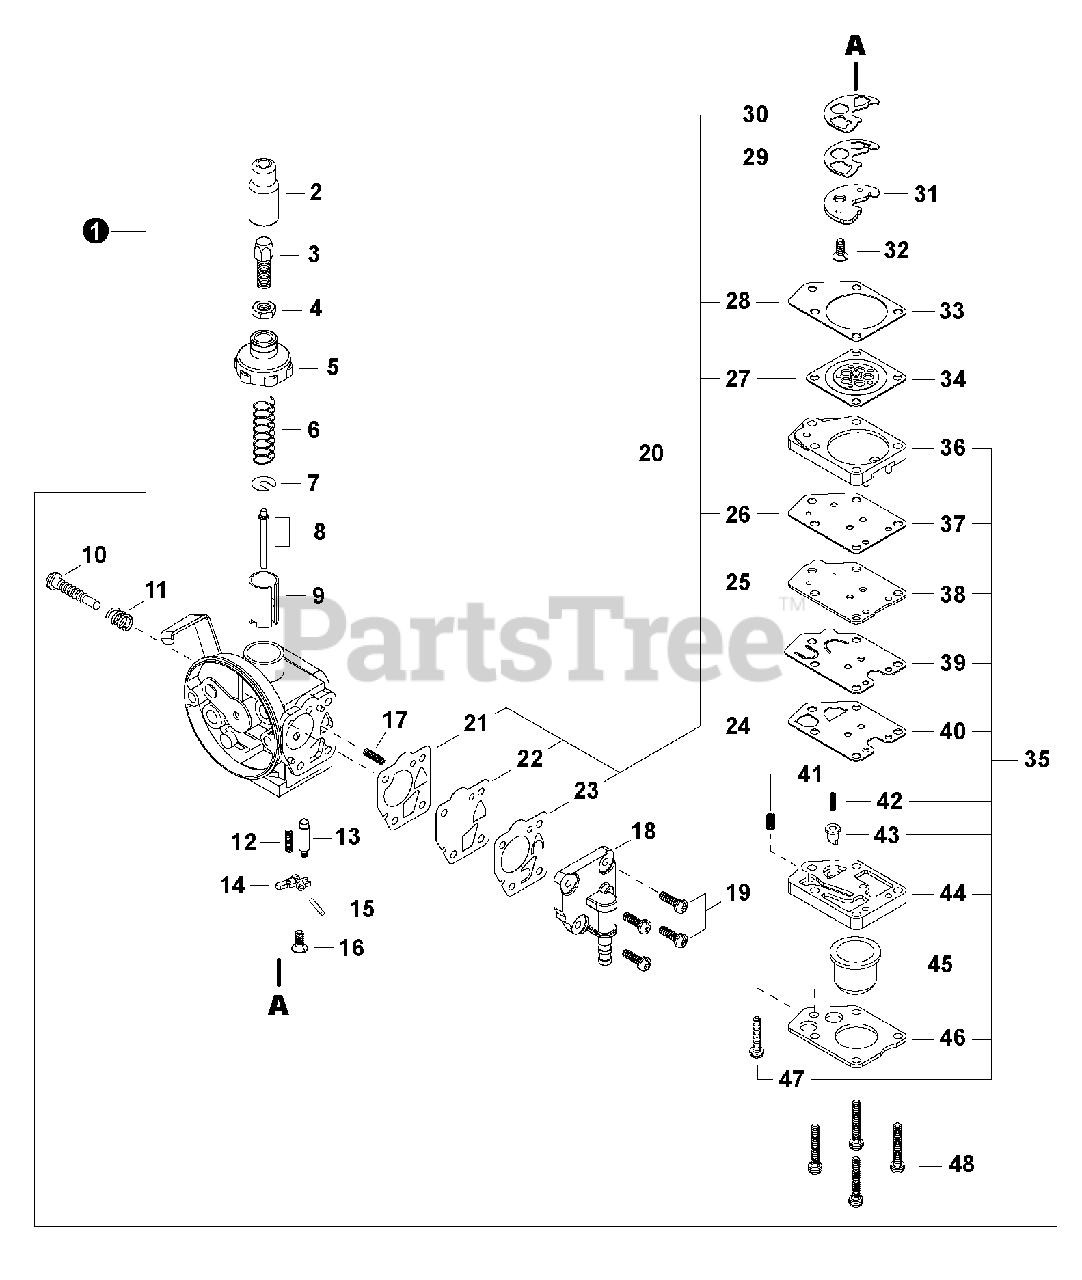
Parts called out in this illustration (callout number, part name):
1	CARBURETOR - DPV10W-18B
3	ADJUSTER, CABLE
4	NUT, LOCK
5	CAP, CARBURETOR
7	WASHER, SPRING SUPPORT
8	NEEDLE, JET
9	VALVE, THROTTLE
10	SCREW, IDLE ADJUST
12	SPRING, TENSION
13	VALVE, INLET NEEDLE
14	LEVER, METERING
15	PIN, METERING LEVER
16	SCREW M3×8
17	SPRING, COIL
18	PUMP BODY
20	GASKET / DIAPHRAGM KIT
21	GASKET, DIAPHRAGM
22	DIAPHRAGM, METERING
23	VALVE, PUMP
24	VALVE, CHECK
27	DIAPHRAGM, METERING
28	GASKET, METERING DIAPHRAGM
29	VALVE, CHECK
30	PACKING
32	SCREW M3×8
33	GASKET, METERING DIAPHRAGM
34	DIAPHRAGM, METERING
35	PURGE PUMP KIT
36	COVER, PUMP
39	PLATE, PUMP
40	VALVE, CHECK
43	VALVE, CHECK
44	BODY, PURGE
45	BULB, PURGE
46	RETAINER, PURGE BULB
48	SCREW 3×20
